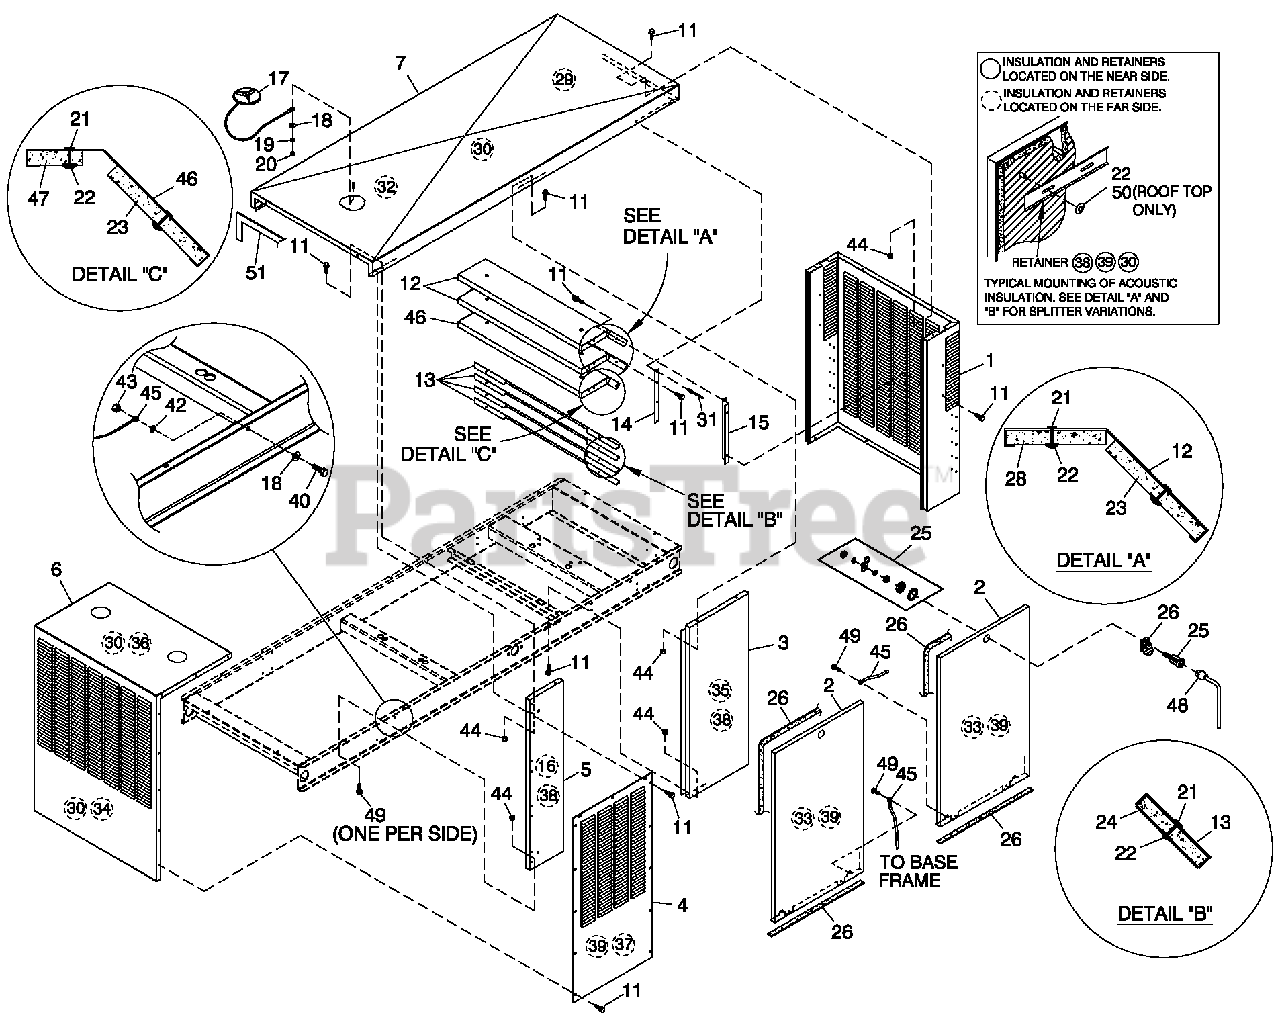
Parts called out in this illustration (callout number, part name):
1	REAR WRAP C5
2	DOOR C5
3	CENTER SUPPORT C5
4	DISCHARGE DUCT LH & RH SIDE C5
5	FRONT CORNERS C5
6	DISCHARGE CENTER DUCT C5
7	ROOF C5 ALUM
11	SCREW THF M6-1 X 16 N WA Z/JS
12	SPLITTER
13	SPLITTER SHORT
14	STRINGER SPLITTER C3
15	SUPPORT SPLITTER C5 130KW
16	INSULATION CORNER POST
17	ASSEMBLY COVER ACCESS
18	WASHER FLAT 1/4-M6 ZINC
19	WASHER LOCK M6-1/4
20	NUT HEX 1/4-20 STEEL
21	INSULATION RETAINMENT HANGER
22	WASHER SELF LOCKING DOME #4-40
23	INSULATION SPLITTER
24	INSULATION SHORT LOUVER
25	VISE-ACTION LATCH SLOTTED CIR
26	GASKET EXTRUDED TRIM (566" LG)
27	TAB PULL
28	INSULATION SPLITTER SML
29	INSULATION ROOFTOP REAR
30	RETAINER INSULATION (740)
31	RIVET POP ,1875 X ,450 SS
32	INSULATION ROOFTOP
33	INSULATION DOOR
34	INSULATION DISCHARGE DUCT
35	INSULATION CENTER SUPPORT
36	INSULATION DISCHARGE DUCT TOP
37	INSULATION INNER DUCT SIDE
38	RETAINER INSULATION (820)
39	RETAINER INSULATION (450)
40	SCREW HHC M6-1,0X20G8,8
42	WASHER SHAKEPROOFINT1/4
43	NUT H E X M 6X 1,0G 8Y E L CHR
44	NUT HEX LOCK M6-1,0 SS NY INS
45	ASSY WIRE 14 AWG 34,8" GRN/YEL
46	SPLITTER C5
47	INSULATION SPLITTER SHRTMPS
48	KEY VISE-ACTION LATCH SLOT CIR
49	SCREW TH-FRM M6 W/CAP SHKPRF W
50	WASHER SELF LOCKING DOME #8-32
51	STRIP SEALANT 1/8 X 1 (44,52"LG)
